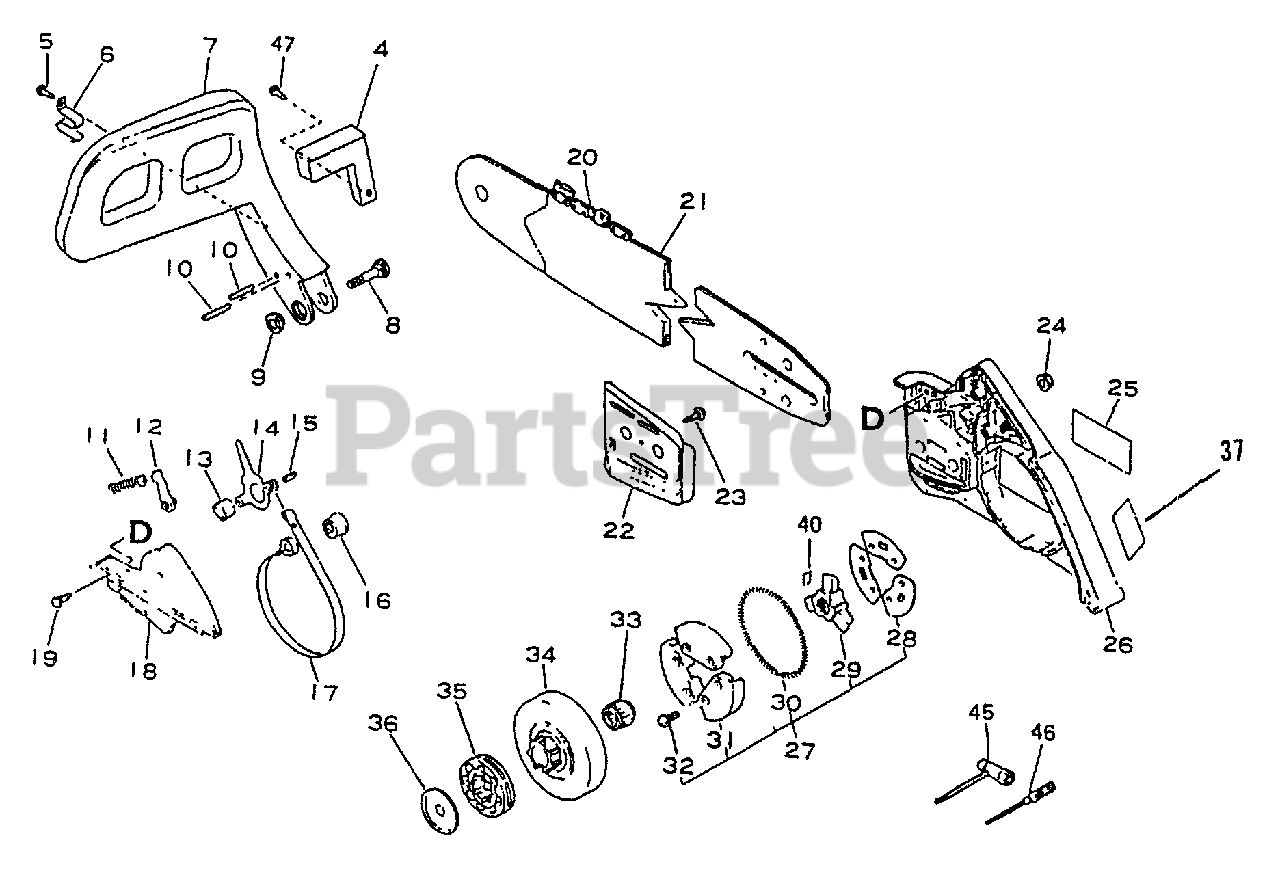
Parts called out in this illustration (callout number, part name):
4	WEIGHT, BRAKE
5	SCREW 5×14
6	SPRING, RETURN
7	LEVER, BRAKE
10	PIN 3×24
11	SPRING, COMPRESSION
12	STOPPER, BRAKE
13	SPACER 8×12×9
14	LEVER, BRAKE
15	PIN, SPRING 4×8
16	ADJUSTER, BRAKE
17	BAND, BRAKE
18	COVER, BRAKE
19	SCREW TAPPING 4×14
20	SAWING CHAIN - 16" -- PRO GUARD
20	SAWING CHAIN - 18" -- PRO GUARD
21	GUIDE BAR - 16" -- DOUBLE GUARD
21	GUIDE BAR - 18" -- DOUBLE GUARD
22	PLATE, GUIDE - INNER
23	SCREW 4×8
24	NUT, FLANGE M8×1.25
25	LABEL - ECHO
26	GUARD, SPROCKET
27	CLUTCH ASSY
28	PLATE, CLUTCH
29	HUB, CLUTCH
30	SPRING, CLUTCH
31	SHOE SET, CLUTCH (3PCS)
32	SCREW 4×8
33	BEARING, NEEDLE
34	DRUM, CLUTCH
35	SPROCKET, 0.325 RIM
45	T-WRENCH 13×19×180
46	SCREWDRIVER, PHILLIPS
47	SCREW 4×14
